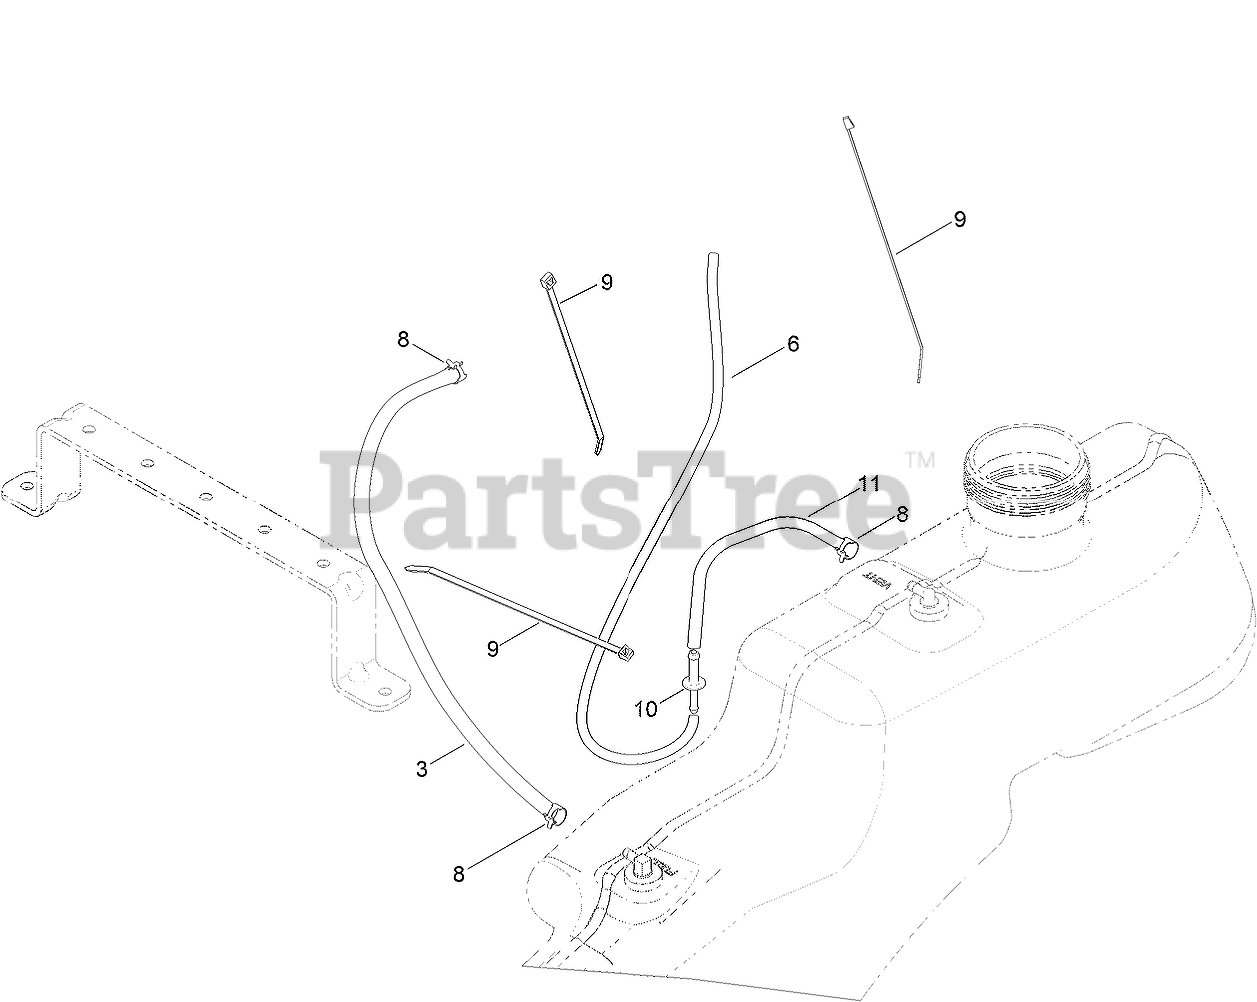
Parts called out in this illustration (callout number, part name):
3	HOSE-FUEL
6	HOSE-FUEL
8	CLAMP-HOSE
9	TIE-CABLE
10	ADAPTOR-ORIFICE
11	HOSE-FUEL
